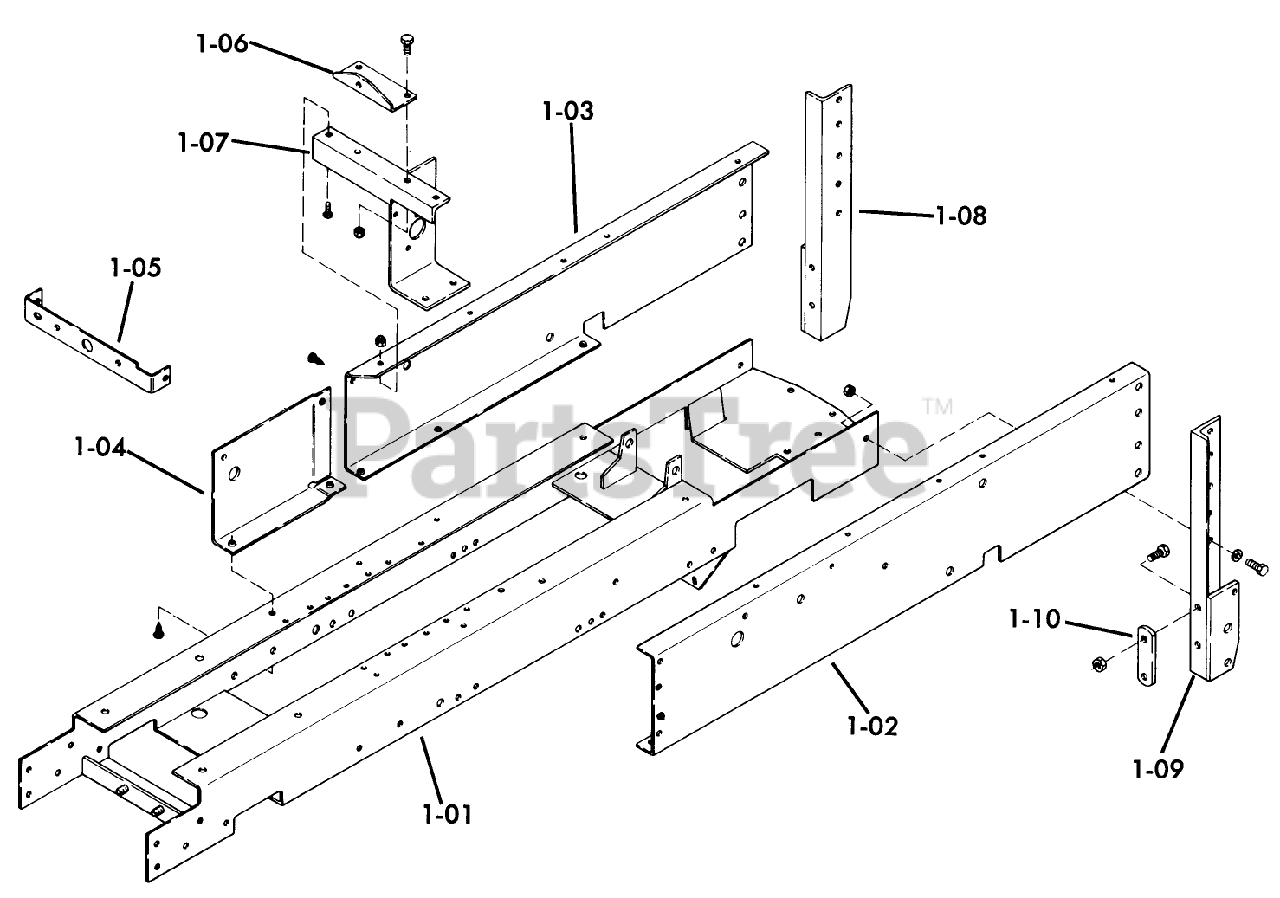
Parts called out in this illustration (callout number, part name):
1-01	Assy-Frame
1-02	Bolt
1-03	Bolt
1-04	Bolt
1-05	SCREW
1-05	WASHER 5/16 SAE
1-06	WASHER 5/16 SAE
1-10	BRACKET-REAR LINK MOUNTING
